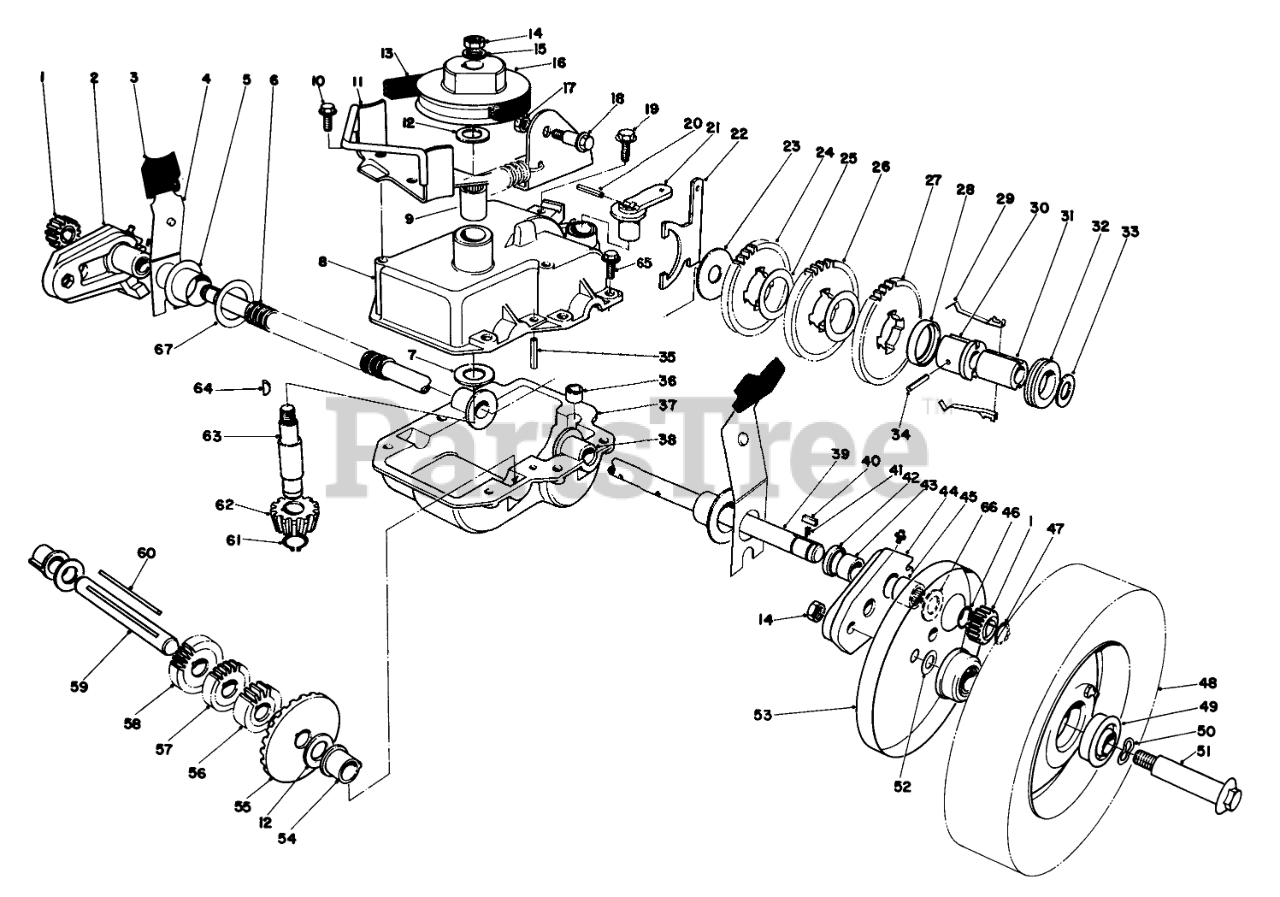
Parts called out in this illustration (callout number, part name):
1	GEAR-PINION
2	Pivot Arm R.H. (Incl. Ref. #42, 43 & 45)
3	KNOB-ARM
4	Spring Arm
5	CAP-END
6	CONDUIT-CONVOLUTED, SPLIT
7	Thrust Washer
8	Case-Upper
9	Bearing
10	Screw
11	Belt Guide Bracket
12	Washer
13	V-BELT
14	Nut
15	Washer
16	PULLEY
18	SHOULDER BOLT
19	Screw-Self Tapping
20	PIN-COIL
21	LEVER-SHIFT
22	Shift Yoke
23	WASHER
24	Gear-38T
25	Washer
26	Gear-40 Tooth
27	GEAR-42T
28	KEY RETAINER
29	Key
30	Body-Sleeve
31	SLEEVE
32	COLLAR-SHIFT
33	Washer
34	PIN-SPRING
35	ROLL PIN 3/16 X 1 IN
36	Yoke Bushing
37	LOWER GEAR CASE CAST
38	Bushing
39	Output Shaft
40	KEY RECTANGULAR
41	SPRING-COMPRESSION
42	Seal
43	Bushing
44	Pivot Arm L.H. (Incl. Ref. #42, 43 & 45)
45	Needle Baring
46	RING-EXT GRIP
47	RING-RETAINING
48	Wheel & Tire Assy. (Incl. Ref. #49)
49	BEARING-BALL
50	SPRING WASHER
51	Wheel Bolt
52	WASHER
53	Cover-Wheel
54	Botching Shaft
55	BEVEL GEAR
56	14 T GEAR
57	16 T GEAR
58	GEAR-18T
59	Sort Shaft
60	Key Square
61	RING-RETAINING
62	PINION-BEVEL
63	INPUT SHAFT
64	KEY-WOODRUFF
65	Screw Hex Head
66	Washer
67	Washer
